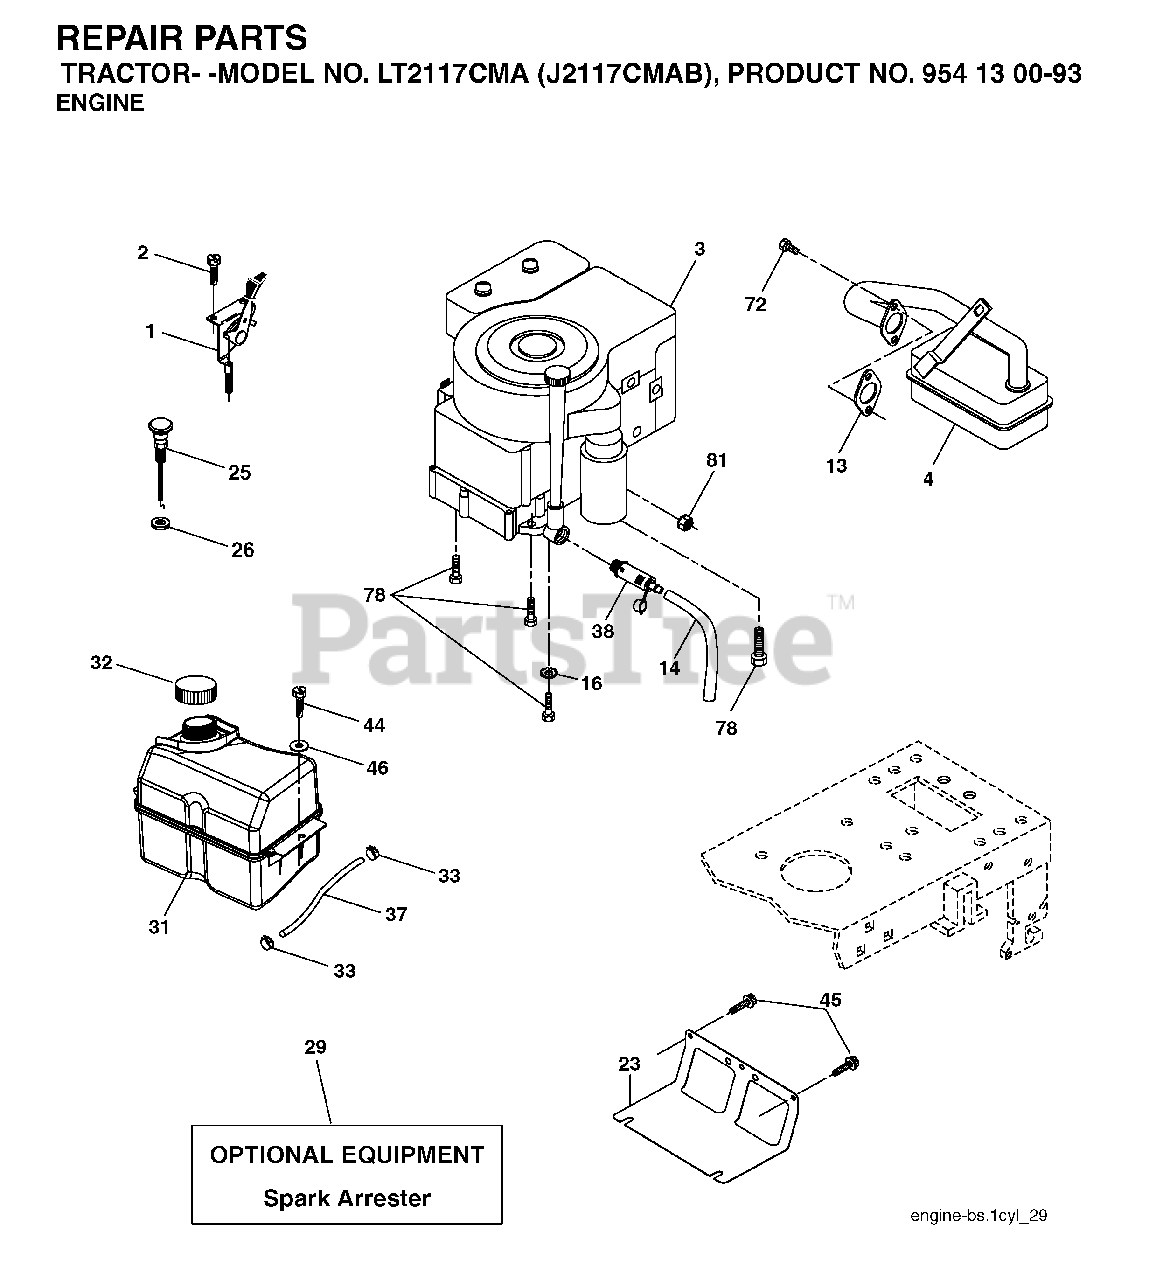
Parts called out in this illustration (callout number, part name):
1	CONTROL.THROTTLE.LT/YT
2	SCREW
4	MUFFLER.SINGLE.CYL.KOHL/B&S
8	BOLT, 5/16-18 X 1 3/4
13	GASKET ENGINE
14	TUBE, DRAIN OIL ASM.
23	SHEILD.BROWNING.DBR.GUARD
29	ARRESTER SPARK (OPTIONAL)
31	TANK FUEL
32	FUEL CAP
33	HOSE CLAMP
37	LINE.FUEL.20
38	PLUG DRAIN OIL EASY
44	SCREW HEXWSHR 1/4-20X3/4
45	SCREW, 3/8-16X3/4
81	NUT
105	SCREW 3/8-16X1
116	NUT.HEX.FLANGE.TOPLOCK
117	TUBE EXHAUST
